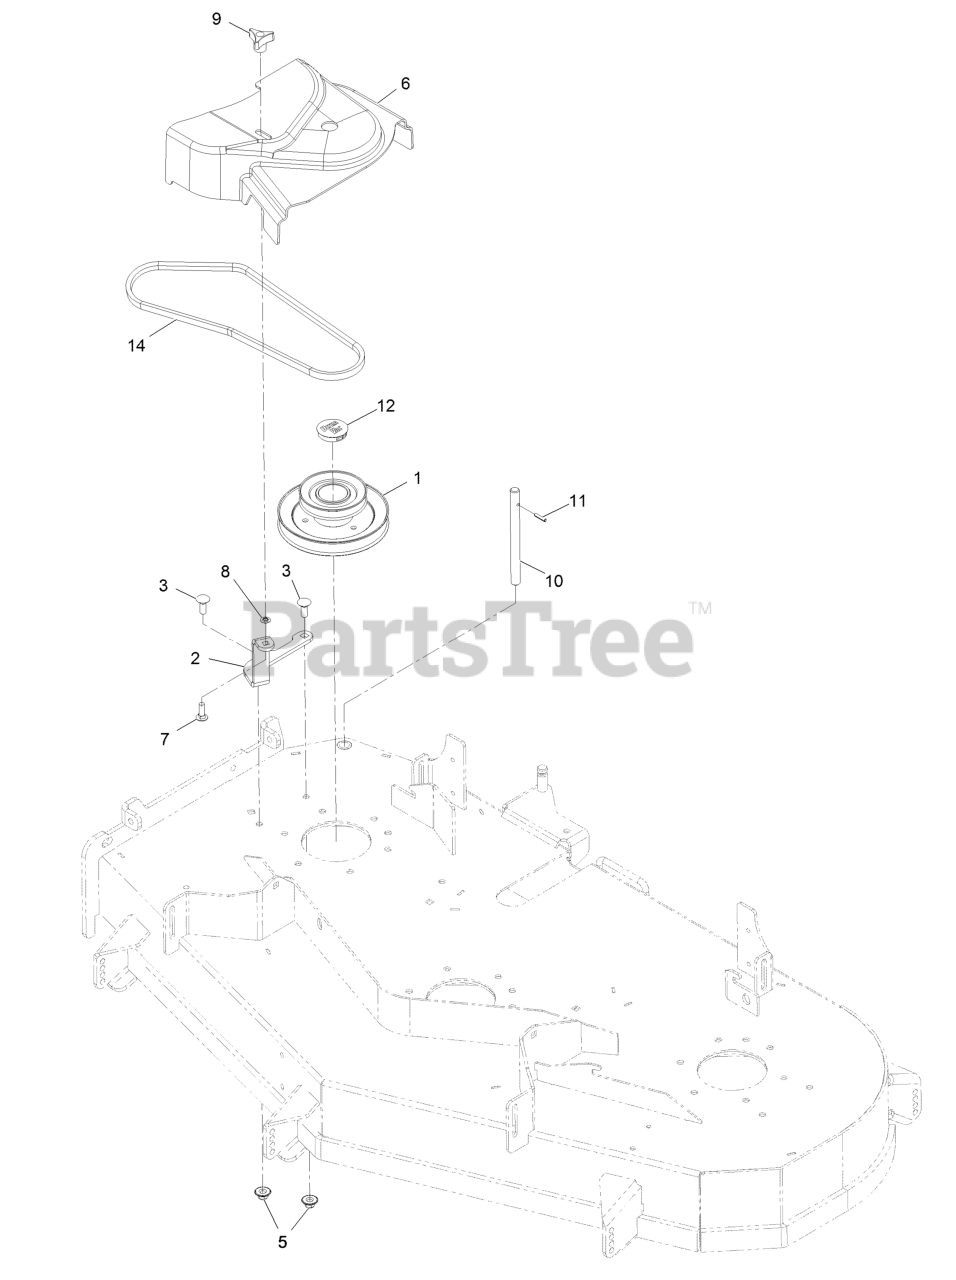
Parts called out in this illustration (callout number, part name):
1	Jackshaft,Uv Drive 524 Splined
2	Bracket, Small Uv Belt Cover
3	Bolt-Carriage 3/8-16 X 1
5	Nut-Nyloc 3/8-16 Flg
6	Cover-Belt, Uv 52
7	Bolt-Carriage 5/16-18 X 1
8	Ring-Bolt Retaining
9	Knob-3 Prong
10	Shaft-Catcher, Grass
11	Rollpin 3/16 X 7/8
14	Belt, Blower Drive 52
